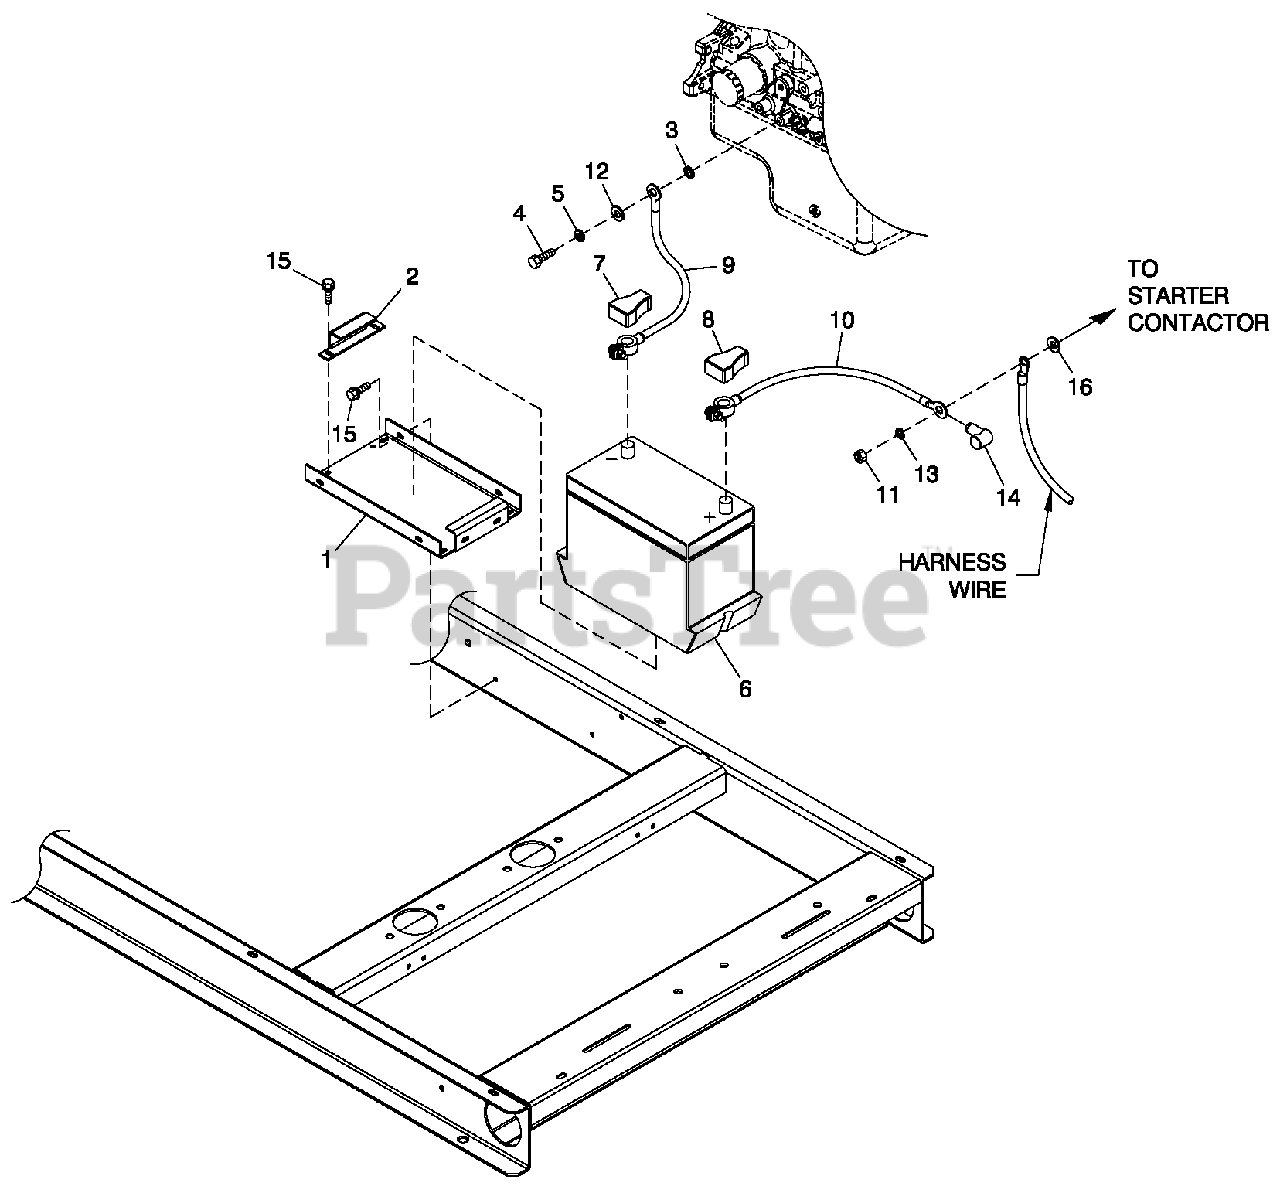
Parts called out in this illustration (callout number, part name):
1	BATTERY TRAY C1 CPL
2	STRAP BATTERY RETAINMENT
3	WASHER SHAKEPROOF EXT 7/16 STL
4	SCREW HHC M10-1.5 X 25 G10.9
5	WASHER LOCK M10
6	BATTERY 12VDC 75-AH 26
7	BATTERY POST COVER RED +
8	BATTERY POST COVER BLK -
9	CABLE BATTERY BLACK #1 X 30.00
10	CABLE BATTERY RED #1 X15.00
11	NUT HEX M8-1.25 G8 YEL CHR
12	WASHER FLAT 3/8-M10 ZINC
13	WASHER SHAKEPROOF EXT 5/16 STL
14	BOOT CONTACTOR CABLES
15	SCREW THF M6-1 X 16 N WA Z/JS
16	WASHER FLAT 5/16-M8 ZINC
